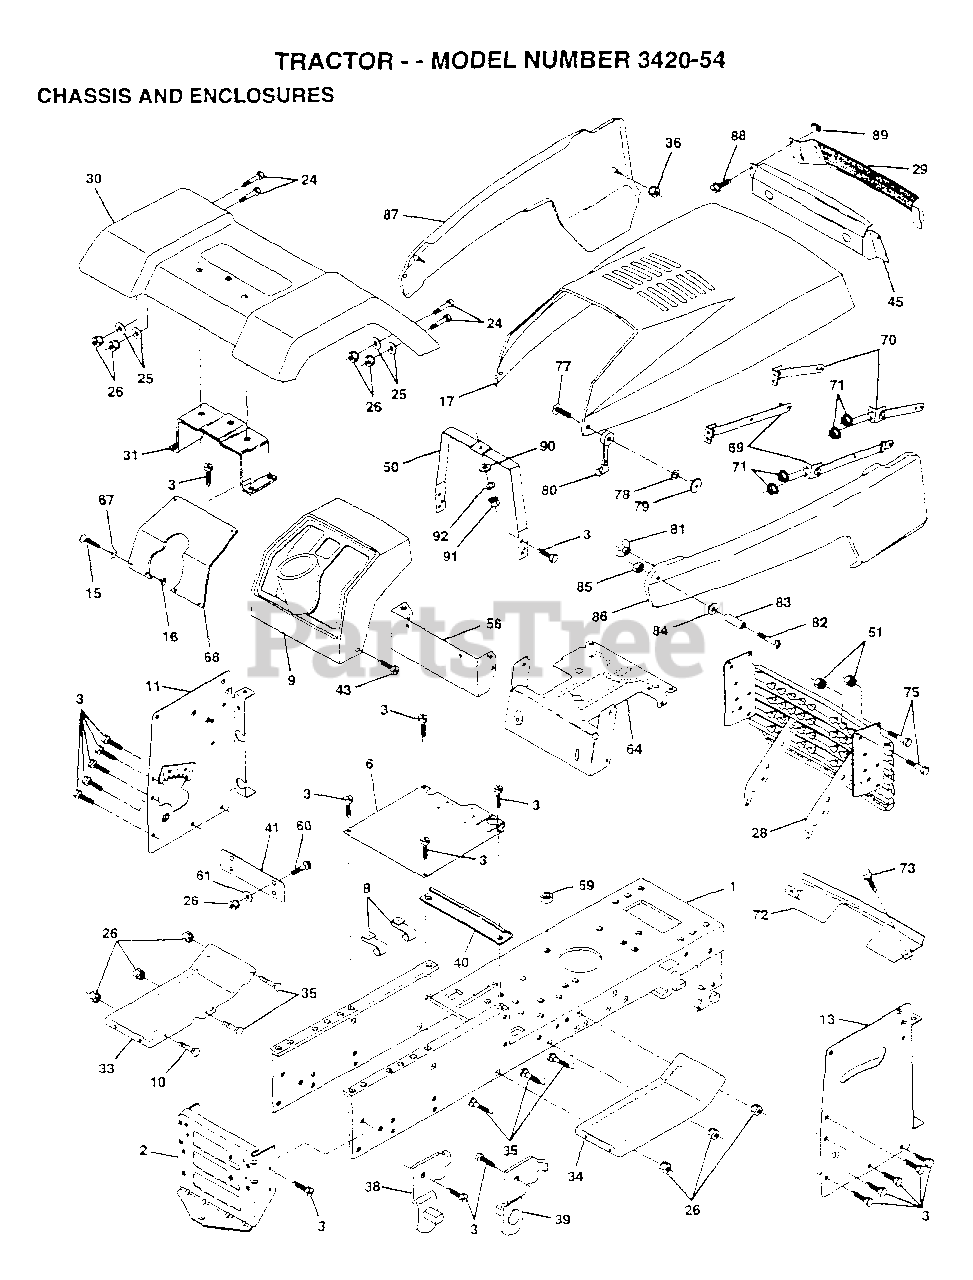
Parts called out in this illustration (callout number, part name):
1	CHASSIS.WLD.11GA
2	DRAWBAR, STRETCH
3	SCREW
8	"CLIP,INSULATOR"
9	DASHBOARD BLACK
11	PANEL.DASH.LH.PNT
13	PANEL.DASH.RH.
15	SCREW
24	BOLT
25	WASHER
26	NUT
29	LENS LT
31	BRACKET SUPT FEND
33	FOOTREST.LH.LT/GT
34	FOOTREST.RH.LT/GT
35	BOLT
36	PAL NUT LT
38	BRACKET ASM LH
39	BRACKET ASM RH
40	SPACER FENDER LT
41	PLATE EXTEN FEND
50	DASH.SUPT.YP/HUSQ
60	BOLT
61	WASHER
66	PLATE.SILKSCREEN
67	WASHER
71	NUT HXKEP 1/4X20
72	STRAP.GRILLE.424
73	SCREW CRT
77	SCREW
78	LOCKWASHER
79	WELDNUT
80	HOOD LATCH T
81	WINGNUT.1/20.NYL.
82	SCREW
83	SPACER LT
84	WASHER
87	"PANEL,SIDE LH"
89	"""J"" FASTENER LT"
90	WASHER PM
92	LOCKWASHER
129	DASH.EXT.PNT.
